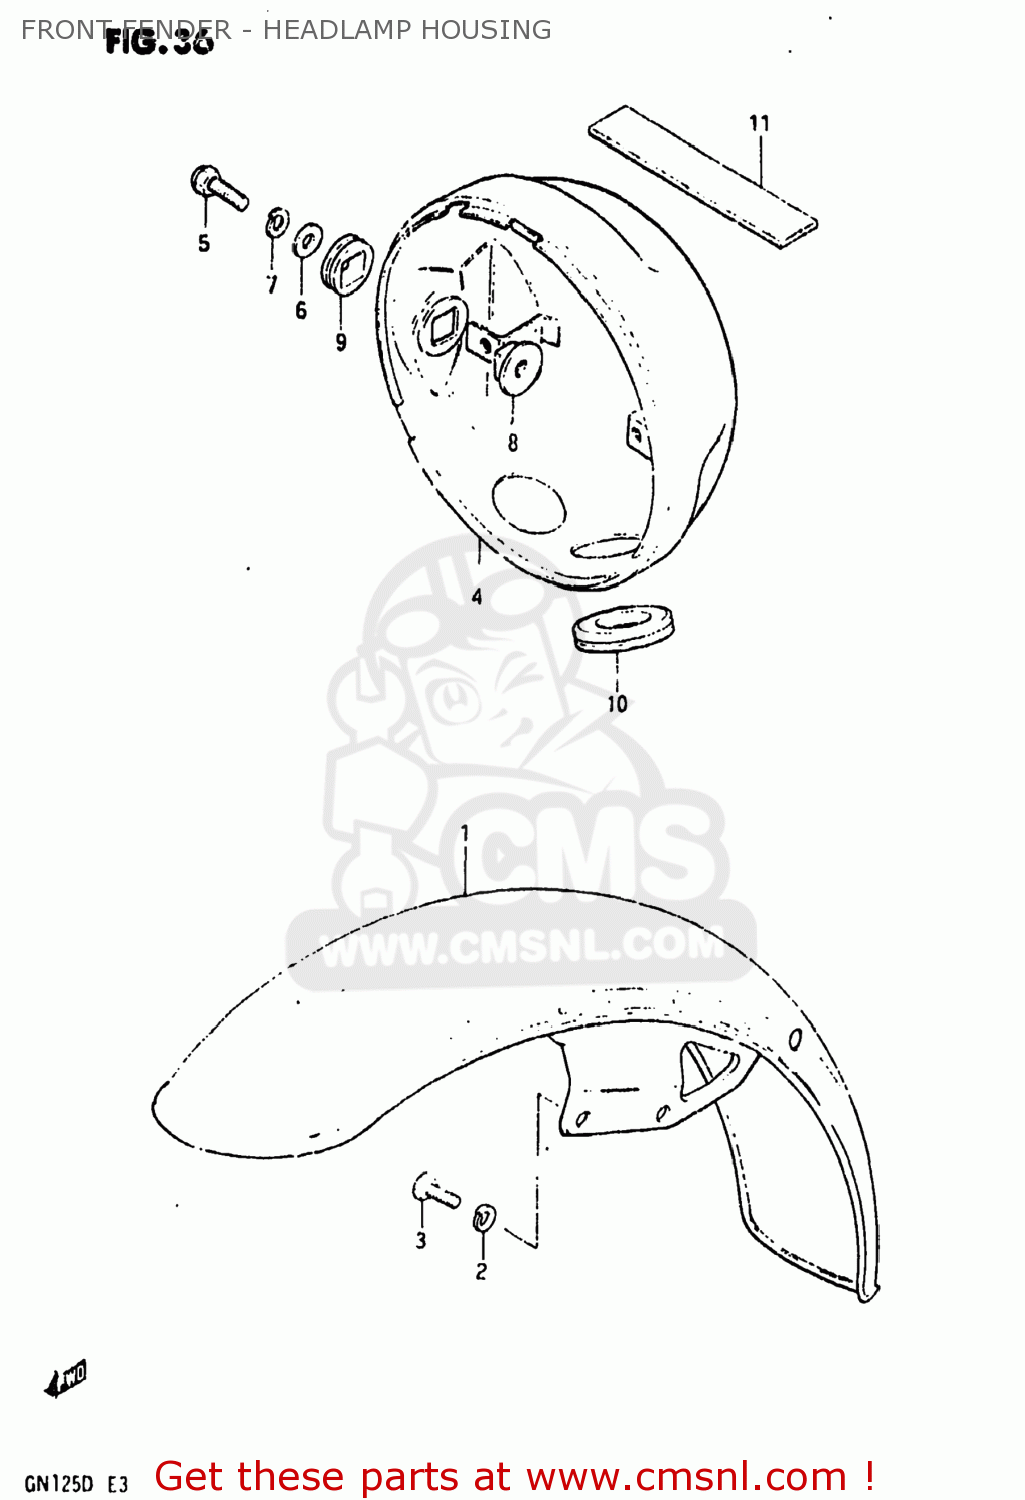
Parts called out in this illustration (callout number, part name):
1	FENDER,FRONT
2	LOCK WASHER
3	BOLT
4	HOUSING,HEADLAMP
5	BOLT
6	WASHER
7	LOCK WASHER
8	SPACER,HEADLAMP HOUSING
9	CUSHION,HEADLAMP HOUSING
10	GROMMET,HEADLAMP HOUSING
11	CUSHION,HEADLAMP HOUSING
